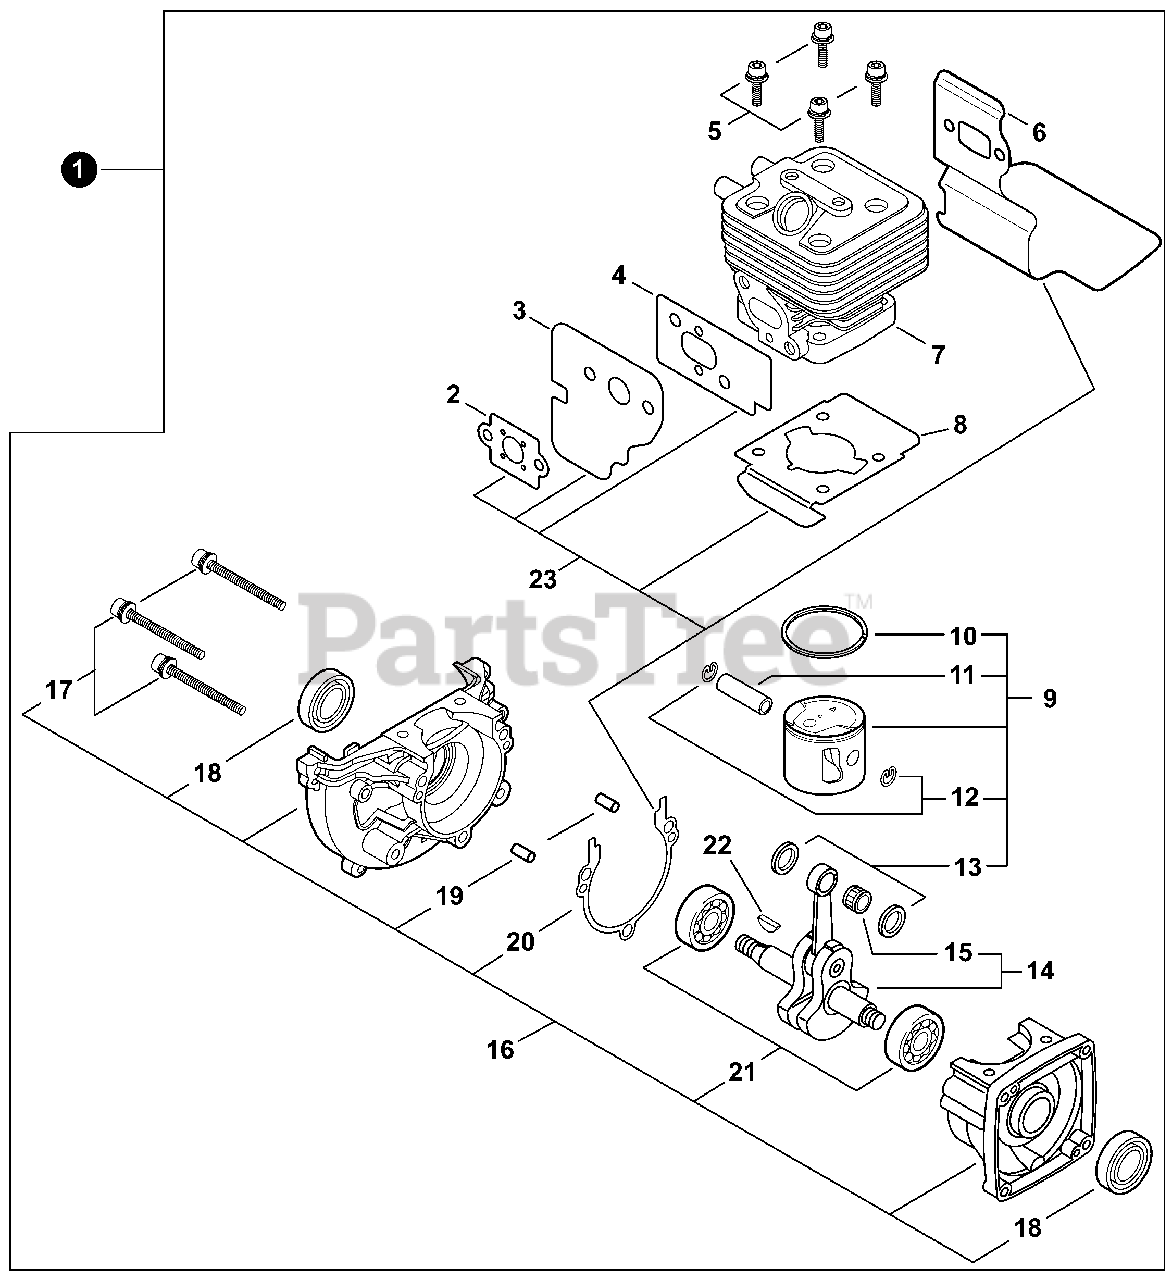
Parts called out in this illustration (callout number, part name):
1	SHORT BLOCK
2	GASKET, INTAKE
3	GASKET, INTAKE
4	GASKET, INTAKE
5	BOLT 5×25
6	HEAT SHIELD, EXHAUST
7	CYLINDER
8	GASKET, CYLINDER
9	PISTON KIT
10	RING, PISTON
11	PIN, PISTON
12	RING, SNAP
13	WASHER, THRUST
14	CRANKSHAFT ASSY
15	BEARING, NEEDLE 8
16	CRANKCASE KIT
17	BOLT 5×28
18	SEAL, OIL 12
19	PIN, LOCATING 4×8
20	GASKET, CRANKCASE
21	BEARING, BALL - 6201 C3
22	KEY, WOODRUFF
23	GASKET KIT
